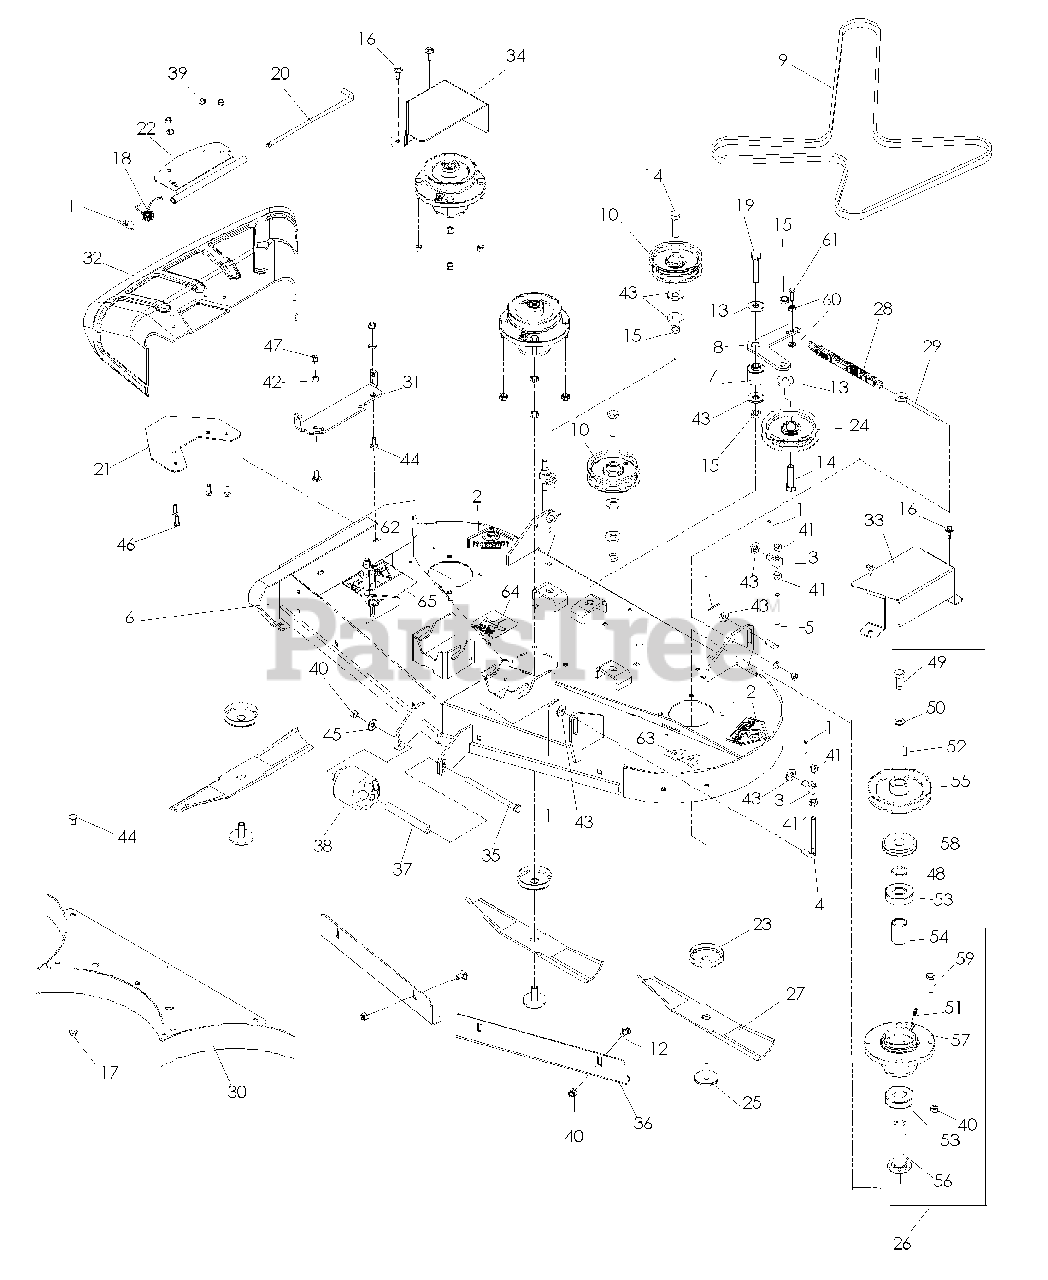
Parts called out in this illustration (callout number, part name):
1	COTTER PIN 1/8 X 3/4
2	DECAL, CPSC
4	L BOLT, S
5	L BOLT, L
6	DECK W/DECAL RAM 44"
7	IDLER SPACER
8	IDLER ARM - 44" DK BLUE
9	V-BELT, 161B
10	PULLEY IDLER
11	PIN, COTTER 1 3/4
12	RHSNB 3/8-16 X 3/4 GR5 ZD
13	WASHER-.533IDX1.37OD
14	BOLT 1/2-13 X 2 HH
15	NUT, 1/2-13 THIN PROF NYL
16	SCREW, TAP & DR #12-14 X 3/4
17	5/16-18 FLANGED L-NUT
18	SPRING, TORSION
19	SCREW, 1/2C X 3 HEX CAP
20	DEFLECTOR PIN
21	DEFLECTOR BRKT
22	DEFLECTOR MT BRKT
23	TRASH GUARD
24	IDLER PULLEY
25	BLADE BOLT
26	SPINDLE LH 6305 BRG.
27	BLD 44" HI LIFT FUS
28	SPRING, DECK BELT
29	EYE BOLT 4.5`
30	44 W-BAFFLE WLDT.
32	44 DEFLECTOR
33	GUARD - PULLEY, LH, BLACK
34	PULLEY GUARD - RH, BLACK
35	BOLT 3/8 X 6 GR5
36	BLOW-BY BAFFLE
37	BUSHING
38	ROLLER 3-3/4 DIA. X 4-1
39	NUT 1/4-20 NYLOC
40	NUT 3/8-16 NYLOC
41	NUT 7/16C HEX
42	FLAT WASHER 5/16 SAE
43	WASHER 1/2" FLAT
44	BOLT 5/16C X 3/4" CARRIAGE
45	WASHER 3/8 FLAT
46	HCS 1/4C X 3/4 HCS
47	NUT 5/16 NYLOC
48	HUB PULLEY SPACER
49	1/2-20 UNF X 1 1/4 HHBLT
50	WASHER .525 X 1.375 X .25
51	ZERK, 3/16, DRIVE IN
52	OUTER SHAFT KEY
53	BEARING - 6305 - 2RS
56	SHAFT SHORT
57	DECK HUB MACHINED
58	TRASH GUARD
59	HCS 3/8C X 1 1/2
60	NUT 1/4-20 HEX FLG LK ZD
61	HCS 1/4C X 1
62	DECAL, EURO SEVERING
63	DECAL, DECK 44"
64	DECAL, BELT ROUTING (18656)
65	DECAL, DANGER
